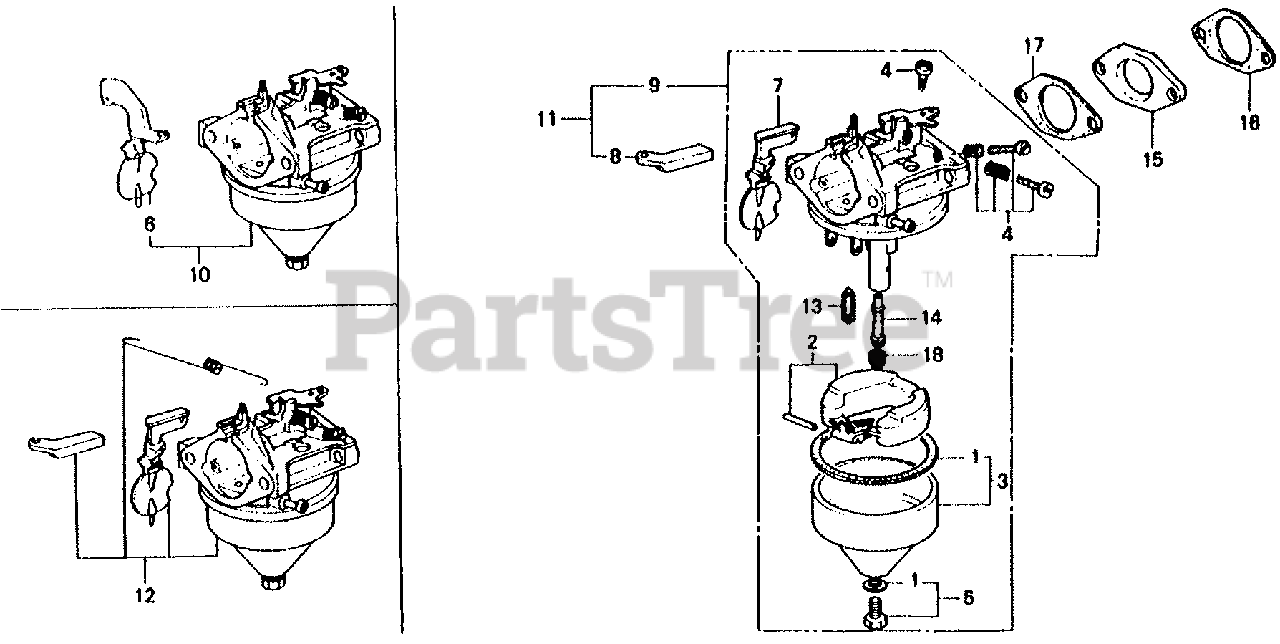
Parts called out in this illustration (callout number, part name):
1	GASKET SET
2	FLOAT SET
3	CHAMBER SET, FLOAT
4	SCREW SET A
5	SCREW SET B
6	CHOKE SET
7	CHOKE SET
8	ARM, CHOKE LEVER
9	CARBURETOR ASSY.
10	CARBURETOR ASSY.
11	CARBURETOR ASSY.
12	CARBURETOR ASSY.
13	VALVE, FLOAT
14	NOZZLE, MAIN
15	INSULATOR, CARBURETOR
16	GASKET, INSULATOR
17	GASKET, CARBURETOR
18	JET, MAIN (#65)
18	JET, MAIN (#68)
18	JET, MAIN (#70)
18	JET, MAIN (#72)
